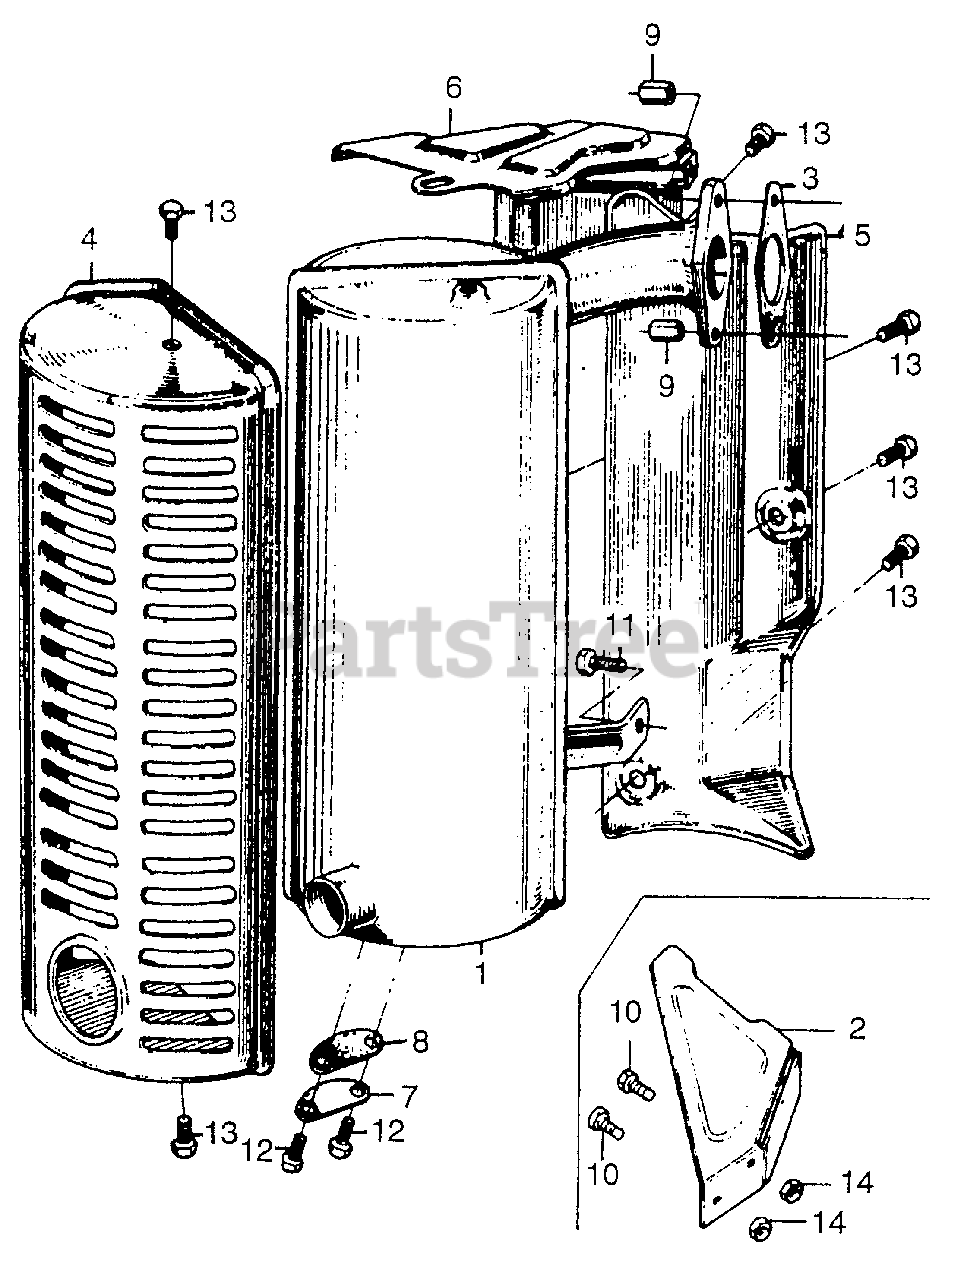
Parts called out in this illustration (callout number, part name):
1	MUFFLER (NOT AVAILABLE)
3	GASKET, MUFFLER (NOT AVAILABLE)
4	PROTECTOR, MUFFLER
5	PLATE, MUFFLER SEPARATOR (NOT AVAILABLE)
6	COVER, EX. PIPE
7	LID, MUFFLER (NOT AVAILABLE)
8	GASKET, MUFFLER LID (NOT AVAILABLE)
9	NUT, HEX. (6MM) (NOT AVAILABLE)
11	BOLT, HEX. (6X16)
12	BOLT, HEX. (6X8) (NOT AVAILABLE)
13	BOLT, HEX. (6X8) (NOT AVAILABLE)
